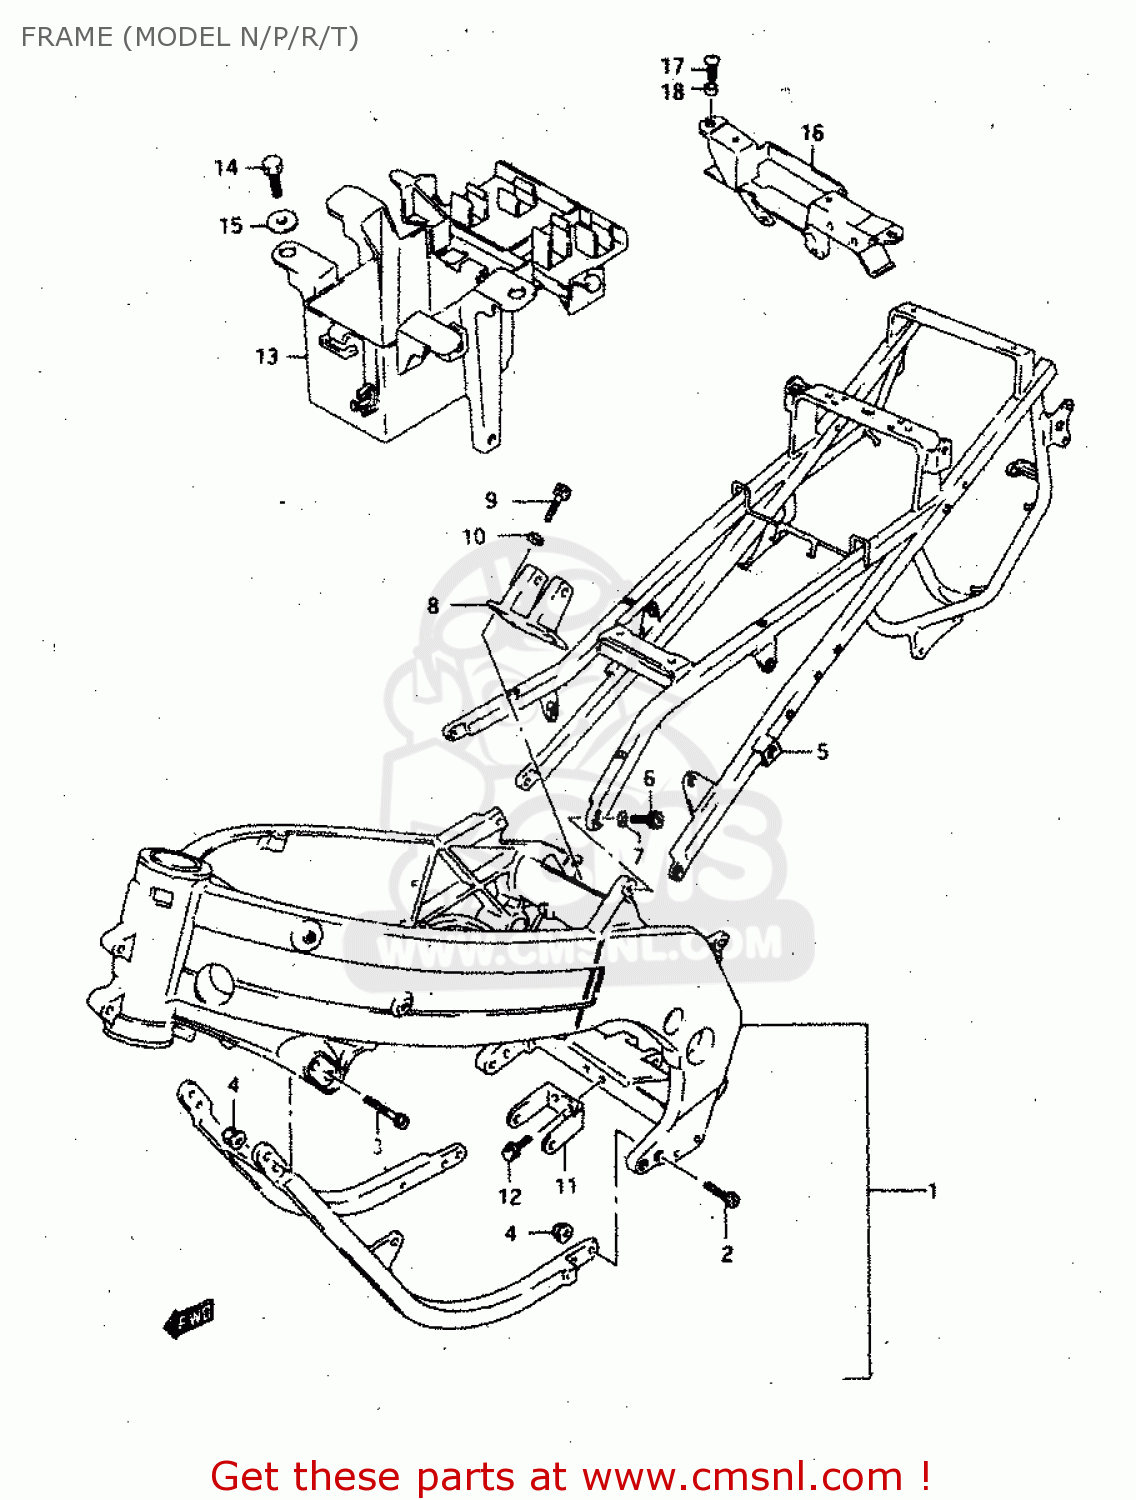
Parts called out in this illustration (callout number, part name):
1	FRAME SET
2	BOLT
3	BOLT
4	NUT
5	SEAT RALE
6	BOLT
7	WASHER
8	BRACKET,R.C.U.
9	BOLT
10	WASHER
11	PLATE, ENGINE MOUNTING
12	BOLT
13	HOLDER, BATTERY
14	BOLT
15	WASHER
16	HOLDER, ELECTRIC PARTS
17	SCREW 6X12
18	SPACER
